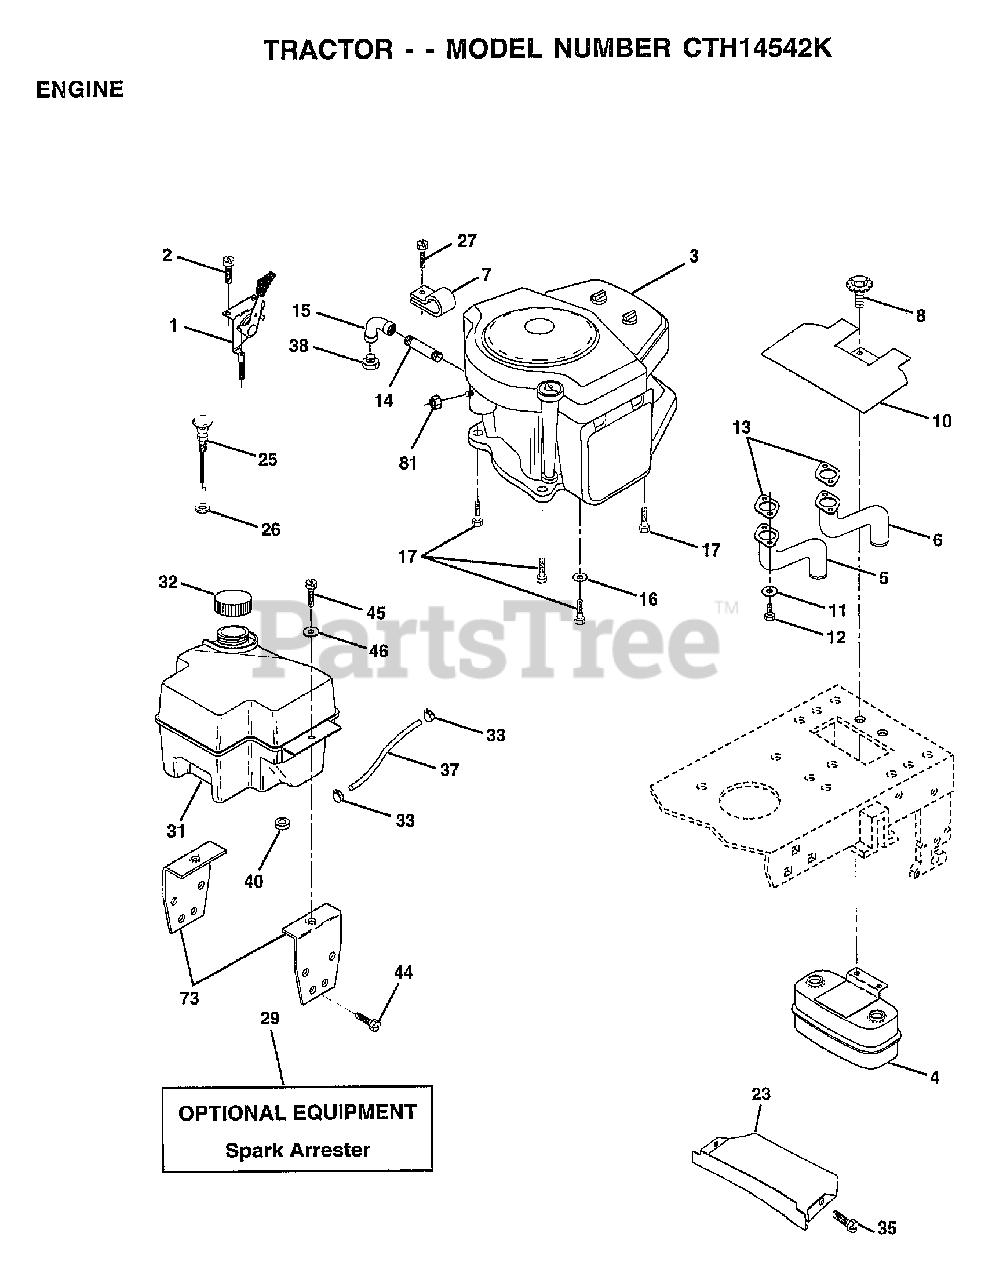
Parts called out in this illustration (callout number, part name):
1	CONTROL.TRTL.37
2	SCREW LT
4	MUFFLER.TW.LOTONE
5	EXHAUST.B&S.18.LH
6	EXHAUST.B&S.18.RH
7	CLAMP.TUBE.DBL.EN
8	BOLT.5/16-18.UNC
10	SHIELD.HEAT.
11	LOCKWASHER
13	GASKET MUFFLER
14	PIPE NIPPLE LT
15	ELBOW
16	LOCKWASHER
17	SCREW LT
23	SHIELD.BRN/DBR.GD
25	"CONTROL.CHOKE.51"""
26	"NUT,KEPS 3/8-24IM"
27	"SCREW-TT,10-32 FL"
31	TANK.FUEL.FRONT.
32	CAP ASM FUEL
33	HOSE CLAMP
35	SCREW
37	LINE FUEL
44	SCREW
45	SCREW HEX CRT
46	WASHER
73	BRACKET.SUPT.TANK
81	NUT
